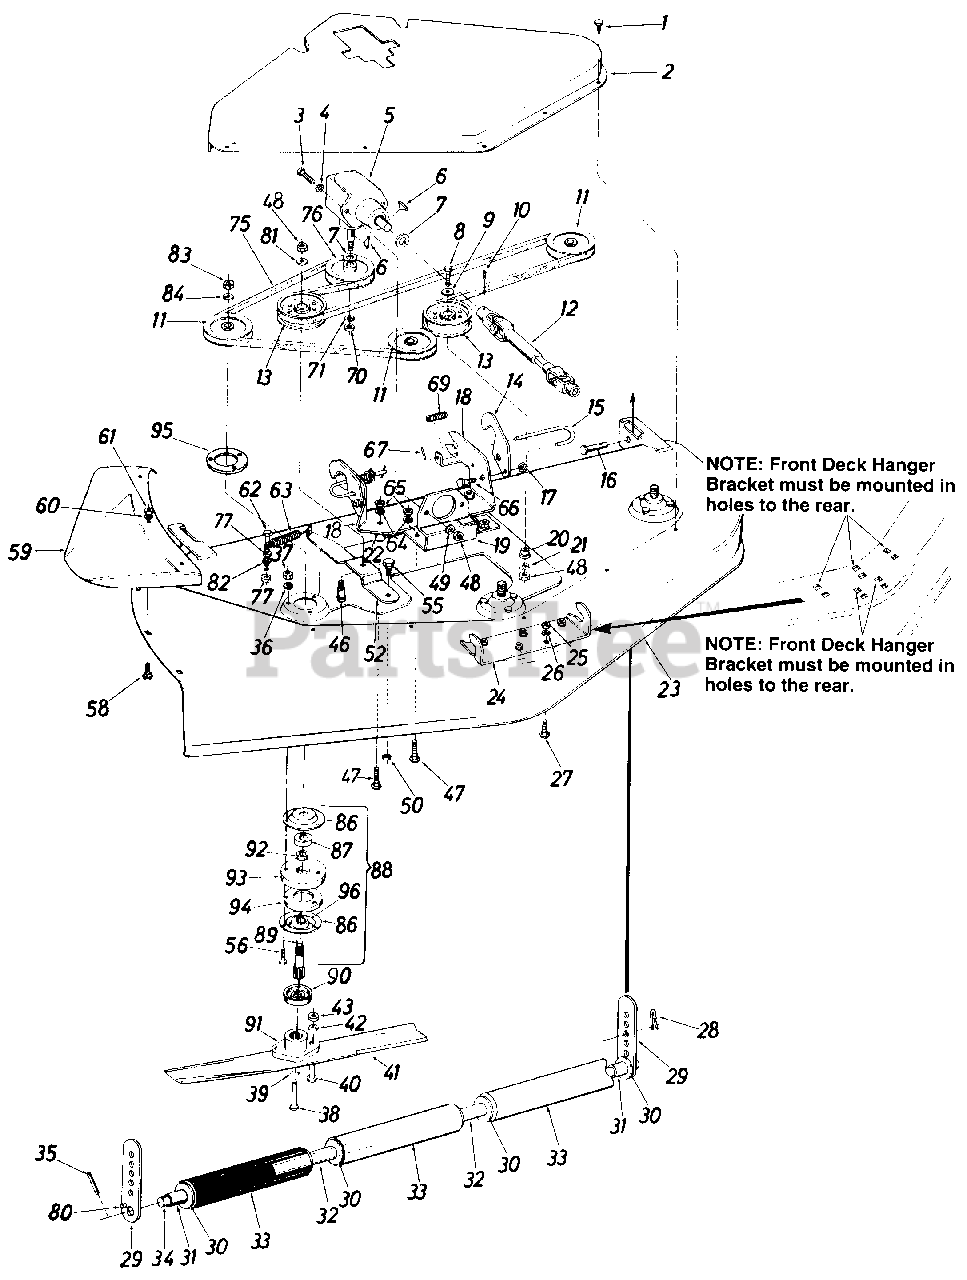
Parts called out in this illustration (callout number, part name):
1	Hex B-Tap Scr. 1/4-20 x .38" Lg.
4	Ext. L-Wash. 3/8" I.D.
5	Right Angle Drive
6	#9 Hi-Pro Key 3/16 x 3/4" Dia.
7	Fl-Wash. 29/32" I.D.
8	Hex Bolt 3/8-16 x 2.25" Lg.
9	Fl-Wash. 3/8" I.D.
10	Sq. Hd. Set Scr. 3/8-16 x .50"
11	Deck Pulley
12	Universal Drive Shaft Ass'y.
13	Deck Idler Pulley
14	Hanger Lock
15	Release Pin
16	Clevis Pin .50" Dia.
17	Hex L-Nut 5/16-18 Thd.
21	L-Wash. 3/8" I.D.
22	Spacer .344" I.D. x 1" O.D.
26	L-Wash. 5/16" I.D.
27	Carriage Bolt 5/16-18 x .75" Lg.
28	Internal Cotter Pin
30	Fl-Wash..75" I.D. x 1.5" O.D.
31	Spacer .758" I.D. x 1.25" O.D. x .530
34	Roller Shaft
35	Roll Pin 3/16 x 1.25"
36	L-Wash. 5/16" I.D.
38	Hex Self-Tap Scr. 3/8-24 x .75" Lg.
39	L-Wash. 3/8" I.D. H.D.
40	Hex Bolt 5/16-24 x 1" Lg.
41	Blade 17"
42	L-Wash. 5/16" I.D.
43	Hex L-Nut 5/16-24 Thd,
46	Shld. Scr..625" Dia. x .96"
47	Carriage Bolt 5/16-1S x 1.5" Lg.
48	Hex Nut 3/8-16 Thd.
49	L-Wash. 3/8" I.D.
50	Hex L-Nut 7/16-14 Thd.
56	Hex Bolt 5/16-24 x 1.5" Lg. (Grade 5)
58	Carriage Bolt 5/16-18 x .75" Lg.
60	L-Wash. 5/16" I.D.
61	Hex Nut 5/16-18 Thd.
62	Hex Bolt 1/4-28 x 1-3/4" Lg.
63	Extension Spring
64	L-Wash. 5/16" I.D.
65	Hex Nut 5/16-18 Thd.
66	Shld. Bolt
67	Roll Pin 1/8" Dia.
69	Compression Spring
70	Hex L-Nut 5/8-18 Thd.
71	L-Wash. 5/8" I.D.
75	"V"-Belt
76	Drive Pulley
77	Hex L-Nut 1/4-28 Thd.
80	Spring Pin Spiral 1/4" Dia. 1.00" Lg.
81	Bell-Wash. 3/8" I.D. x .87" O.D.
82	L-Wash. 1/4" I.D.
83	Hex Jam Nut 5/8-18 Thd.
84	L-Wash. 5/8" I.D.
86	Bearing Housing
87	Ball Bearing
88	Deck Spindle Ass'y.
89	Spindle
90	Bearing Shield
91	Blade Adapter
92	Spacer
93	Spindle Spacer Plate
94	Reinforcement Plate
95	Spindle Reinforcement Plate
96	Open Bearing Housing
